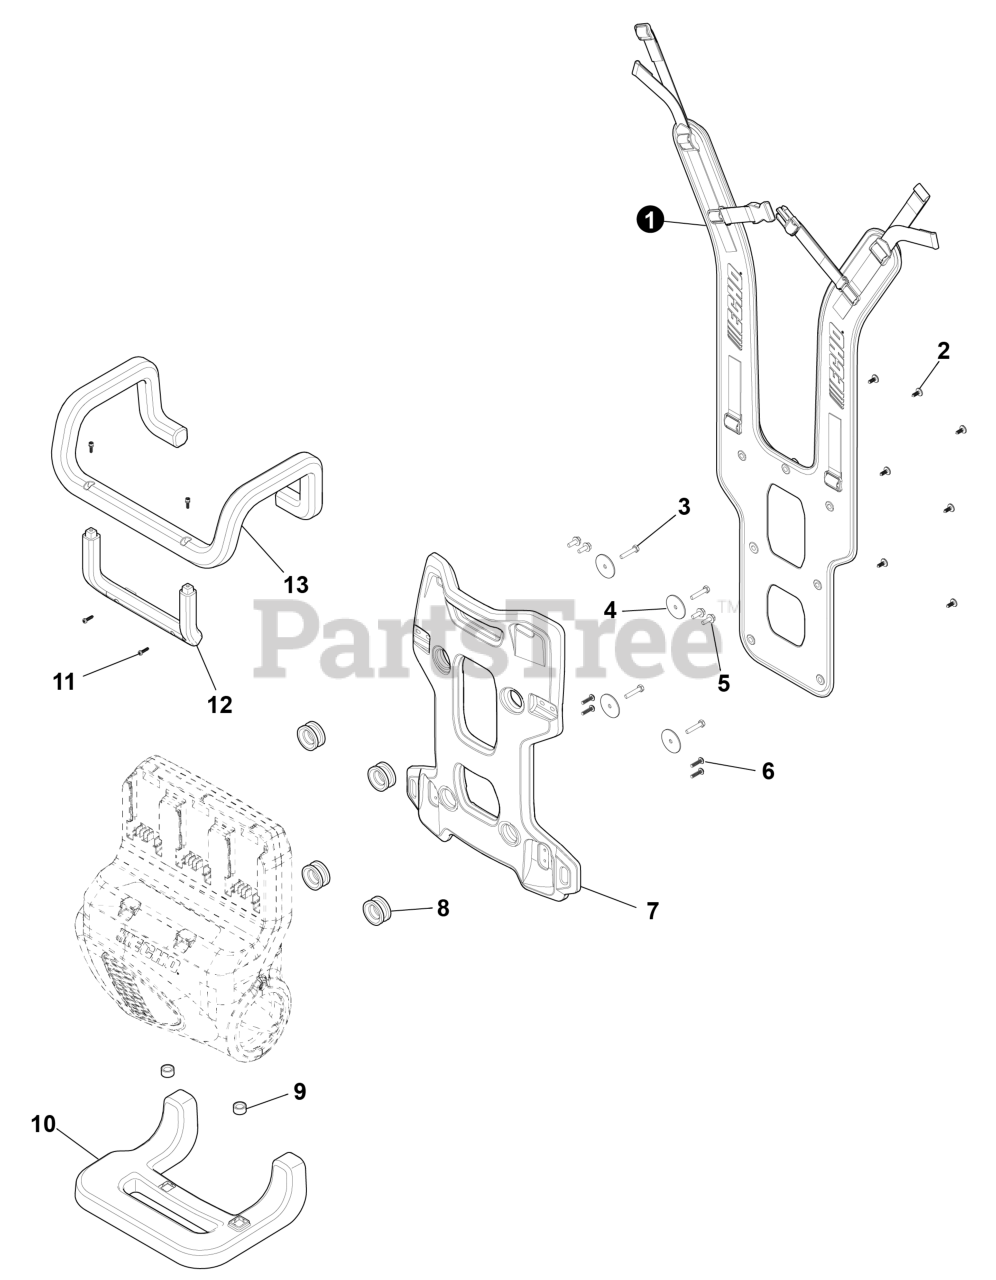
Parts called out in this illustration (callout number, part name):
1	HARNESS ASSY.,SHOULDER
4	WASHER,RUBBER
7	FRAME,REAR
10	FRAME,LOWER
12	FRAME,EXTENSION
13	FRAME,UPPER
